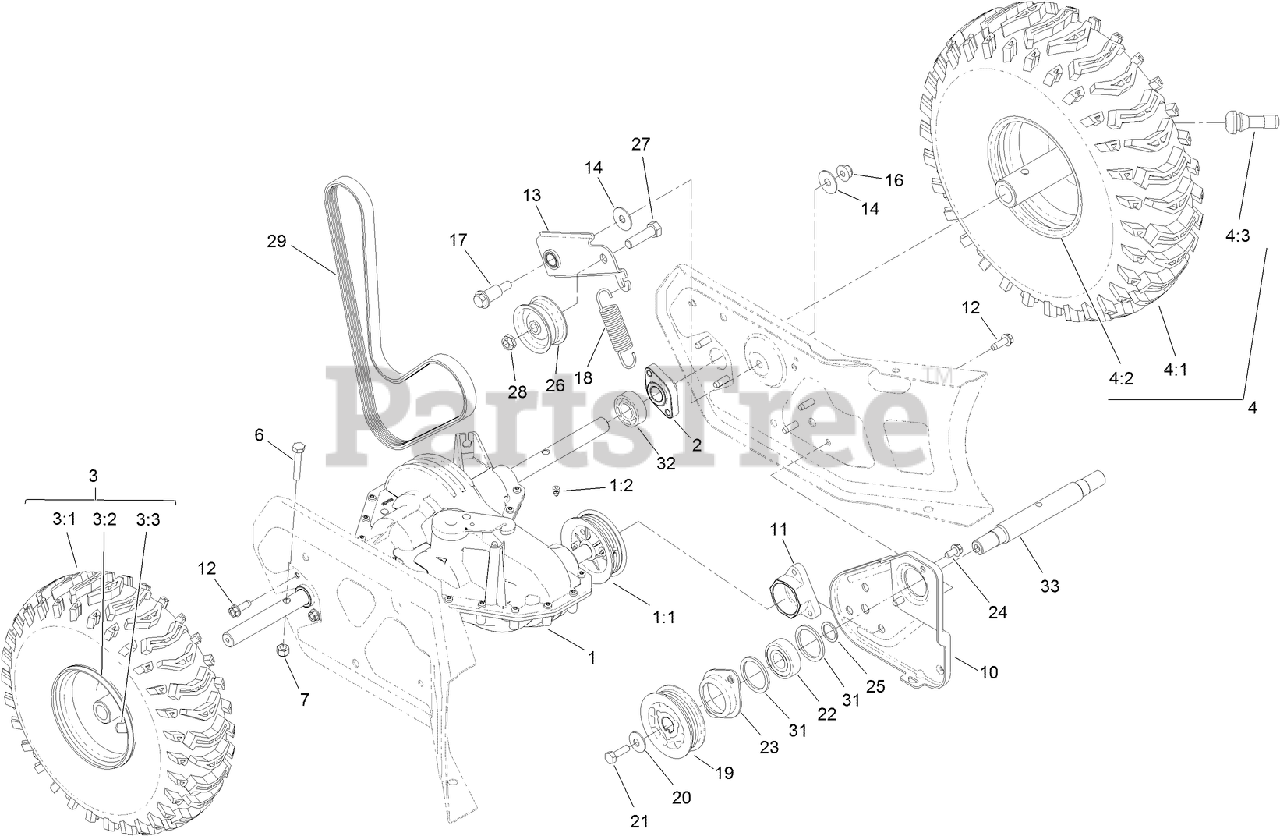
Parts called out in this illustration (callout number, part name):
1	TRANSMISSION
1:1	PULLEY REPAIR KIT
1:2	PLUG-OIL
2	BEARING-AXLE
3	Loose Parts Package
4	Loose Parts Package
6	SCREW-HH
7	NUT-LOCK, NI
10	PLATE-SUPPORT, JACKSHAFT
11	SUPPORT-BEARING
12	SCREW-HWHTF
13	IDLER-TRACTION
14	WASHER
16	NUT-HF, NI
17	BOLT-SHOULDER, HHF
18	SPRING-EXTENSION
19	PULLEY-JACKSHAFT
20	WASHER-BELLEVILLE
21	SCREW-HH
22	BEARING-BALL
23	RETAINER-BEARING
24	SCREW-HWH
25	WASHER-THRUST
26	PULLEY-IDLER, FLAT
27	SCREW-HH
29	BELT-POLY V
31	WASHER-RUBBER
32	SPACER-AXLE
33	JACKSHAFT
